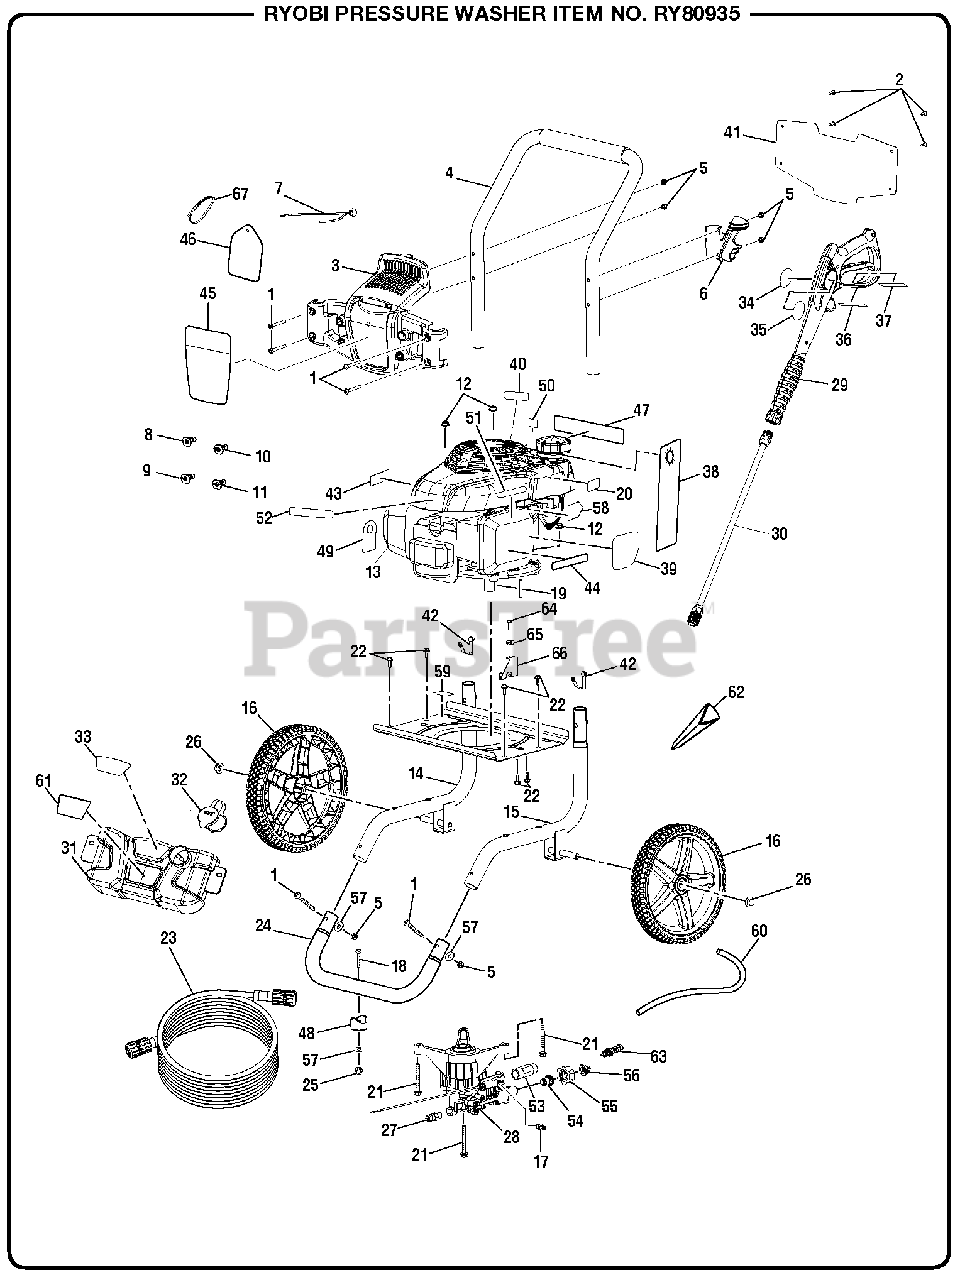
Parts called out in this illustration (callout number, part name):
1	Screw (M6 x 48 mm, T30 Torx Hd.)
2	Screw (#6-20)
3	Hose and Nozzle Holder
4	Handle w/Foam
5	Lock Nut (M6)
6	Wand Holder
7	Bungee Cord Assembly
8	40deg Nozzle
9	Soap Nozzle
10	25deg Nozzle
11	0deg Nozzle
12	Flange Nut (M8 x 1.25)
13	Engine (Honda GCV 160, 160cc OHC Vertical)
14	Main Frame Assembly (Left)
15	Main Frame Assembly (Right)
16	Wheel
17	Detergent Suction Kit
18	Screw (1/4-20 x 1.85 in., T30 Torx Hd.)
19	Output Shaft Key (40 mm)
20	Do Not Mix Label
21	Bolt (M8 x 60 mm, Flange Hd.)
22	Bolt (M6 x 16 mm, Flange Hd.)
23	Hose (25 ft.)
24	Front Frame
25	Lock Nut (1/4-20)
26	Push Cap Nut (1/2 in.)
27	Thermal Release Valve
28	Pump
29	Trigger Handle Assembly
30	Extension Wand
31	Soap Tank
32	Soap Tank Cap
33	Soap Dilution Label
34	Label (Wand Logo)
35	Label (Wand Warning)
36	Warning Label (Fr/Sp)
37	Label (Wand Rating)
38	Danger Hangtag
39	Engine Control Label
40	Combustion Label
41	Quick Start Panel
42	Lock Button w/Spring Clip
43	Hot Surface Label
44	EMC Label
45	Performance Label
46	Nozzle Hangtag
47	Danger Label
49	Dipstick Hangtag
50	No E85 Label
51	Inquiries Label
52	Idle Down Label
53	Outlet Tube
56	Filter Screen (Pump Inlet)
57	Washer (1/4 in.)
58	Engine On/Off Label
59	Oil Fill Location Label
60	Chemical Siphon Tube
61	Powered By Honda Label
63	Pump Unloader Valve
64	Bolt (M5 x 20 mm)
65	Idle Down Cable Clamp
66	Idle Down Cable Bracket
